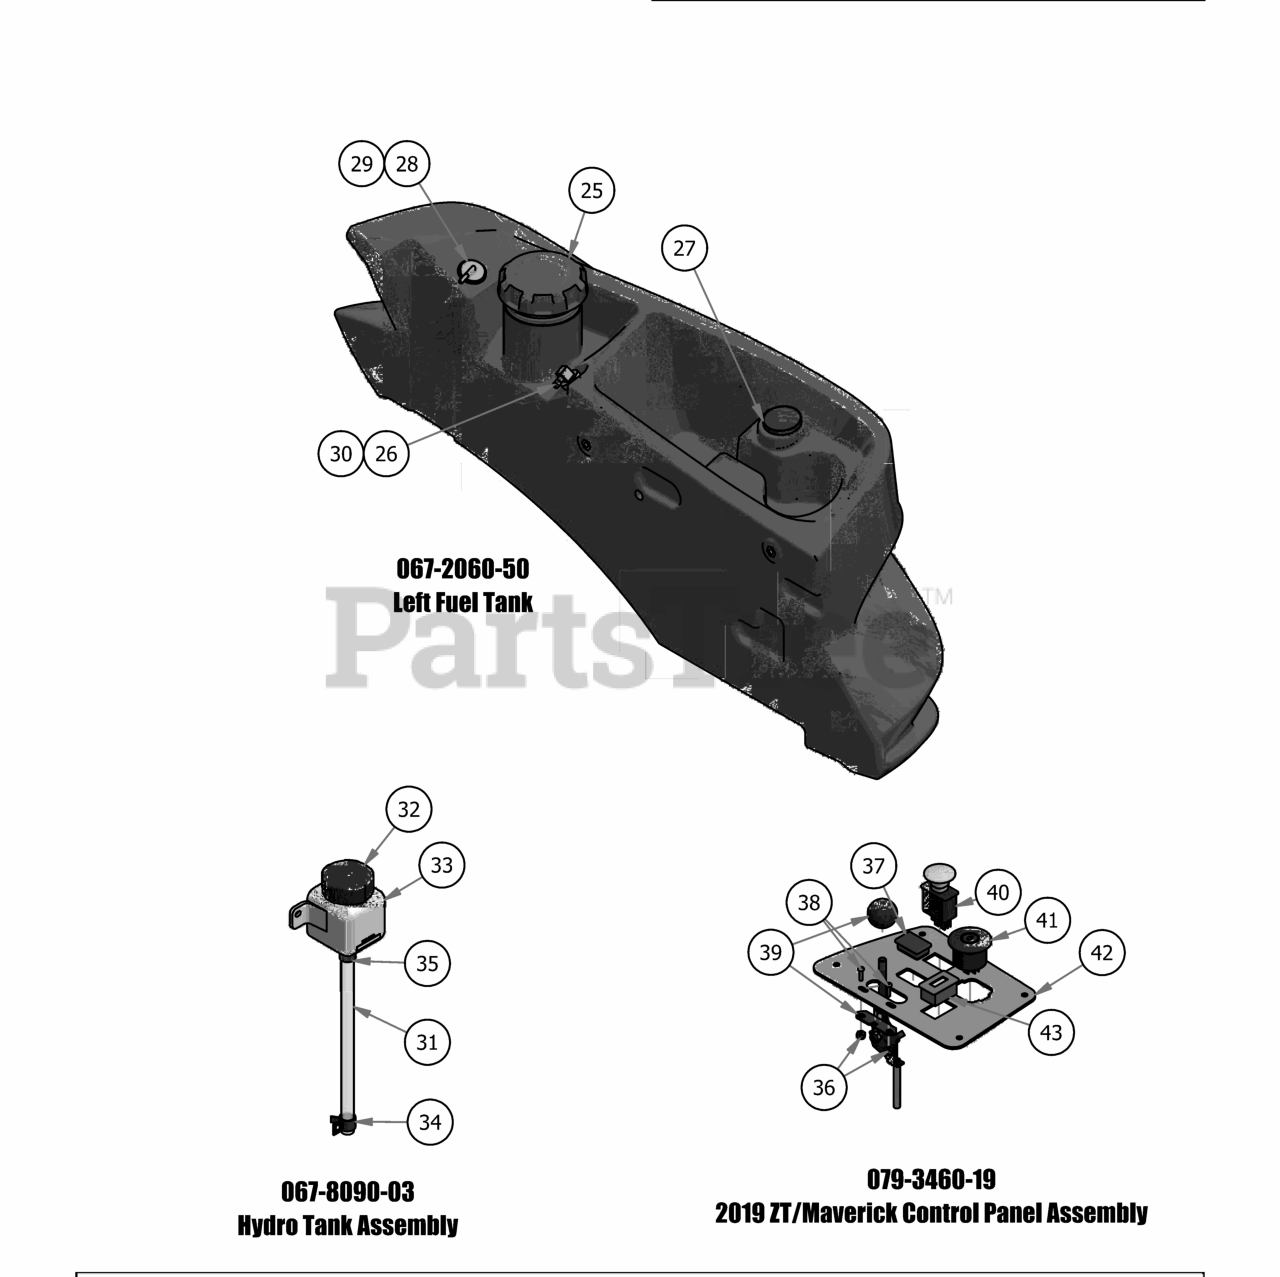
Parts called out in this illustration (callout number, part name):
27	Fuel Gauge w/Grommet
28	Rollover Valve
29	Rollover Valve Grommet
30	Pick-Up Grommet
31	ZT/Maverick Hydro Tank Hose
32	Hydraulic Tank Cap
33	350ml Expansion Tank
34	3/8" Hose Clamp
35	1/2 Hose Clamp
36	10-24 Nylon Insert Locknut Zinc Orange Nylon
37	Light Plug
38	10-24 X 5/8 BS Button Head Bolt
39	Throttle Lever Assembly
40	PTO Engager
41	Ignition Switch
42	Control Panel
43	Tachometer
